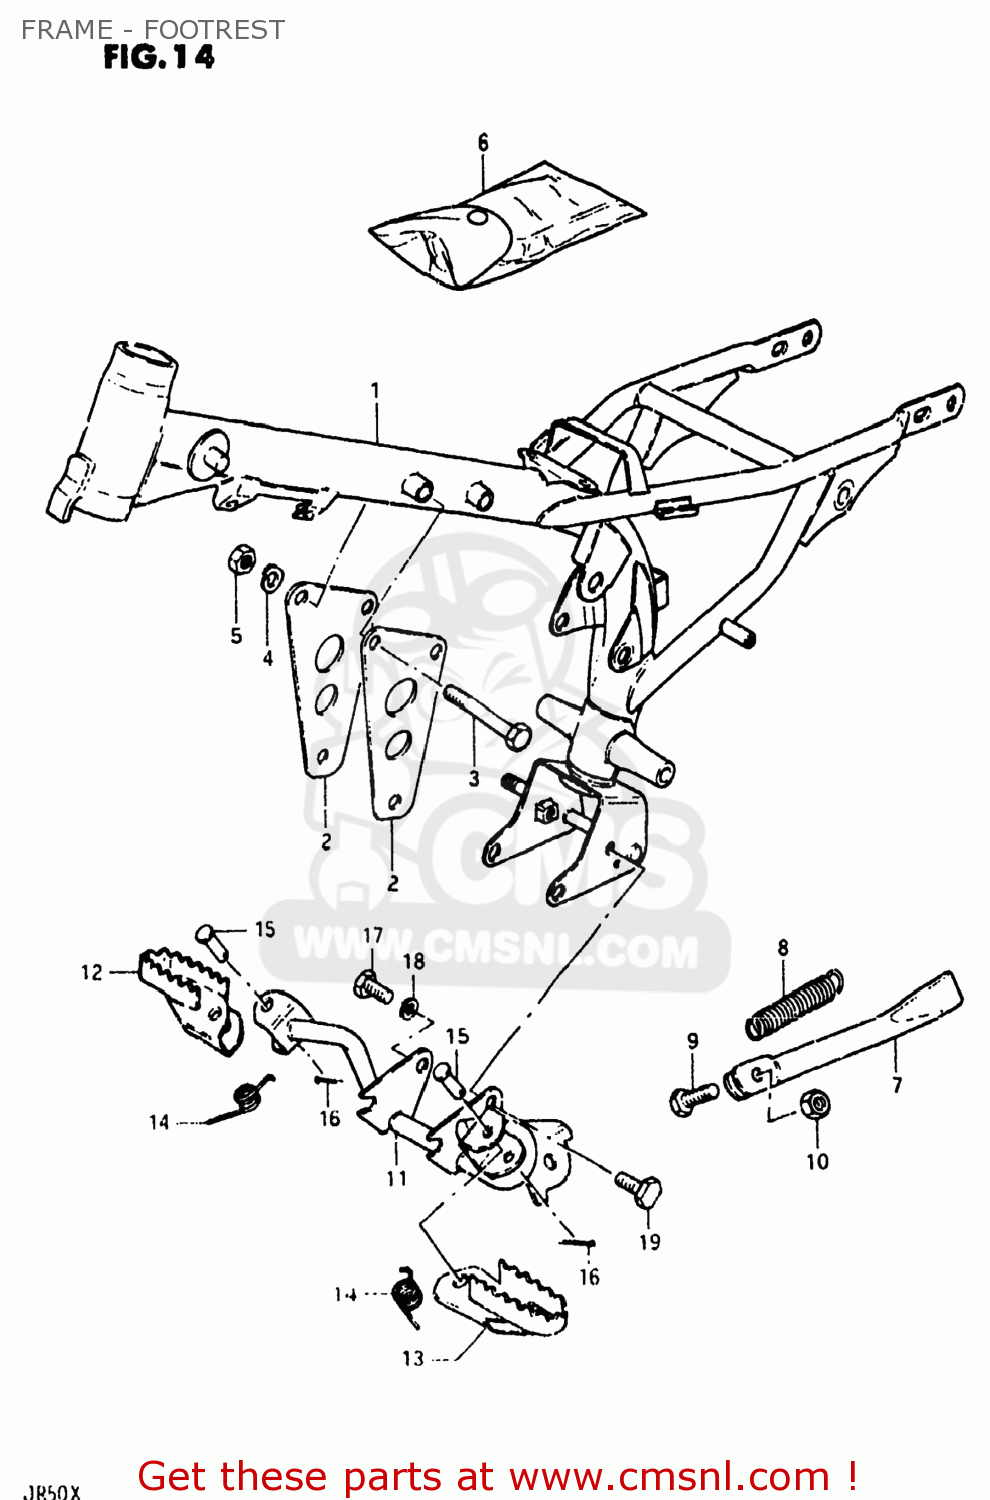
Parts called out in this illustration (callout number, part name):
1	FRAME
2	PLATE,ENG MTG
3	BOLT
4	LOCK WASHER
5	NUT
6	TOOL ASSY
7	STAND,SIDE
8	SPRING
9	BOLT 8X22
10	NUT
11	BAR,FRONT FOOTREST
12	FOOTREST,FRONT,RIGHT
13	FOOTREST
14	SPRING
15	PIN
16	PIN 20X20
17	BOLT
18	LOCK WASHER
19	BOLT(8X14)
